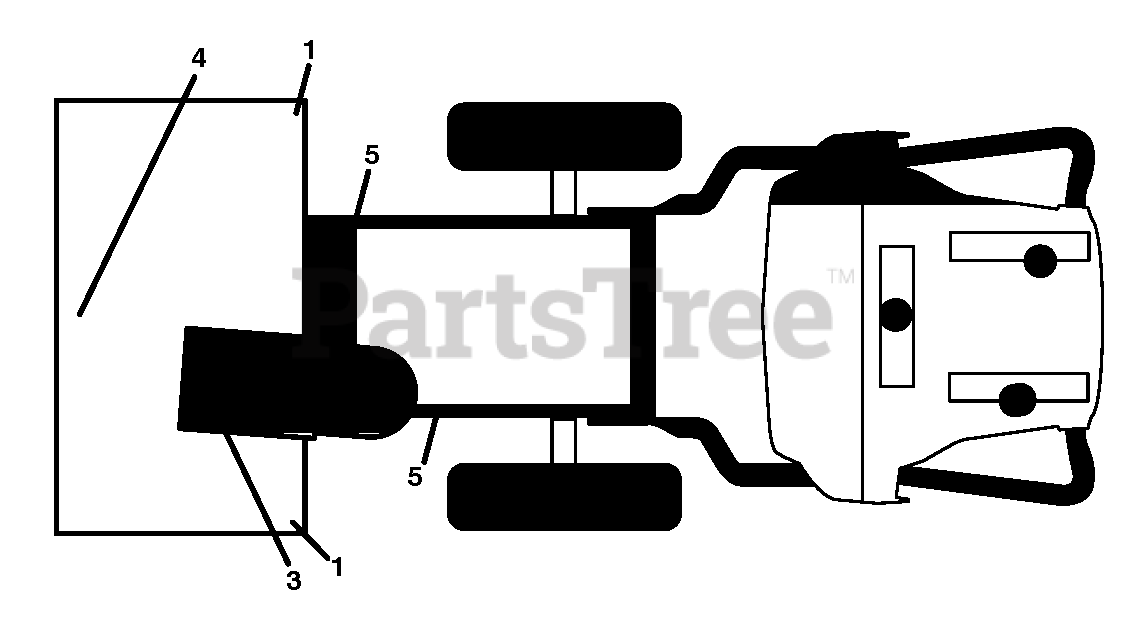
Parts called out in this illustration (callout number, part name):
1	DECAL.AUGER.SAFETY.EU/SC
3	DECAL.CHUTE.SAFETY.EU/SC
4	DECAL.AUGER."READ.OWN.MAN"EU/S
5	DECAL.BELT.GUARD.CAUT
